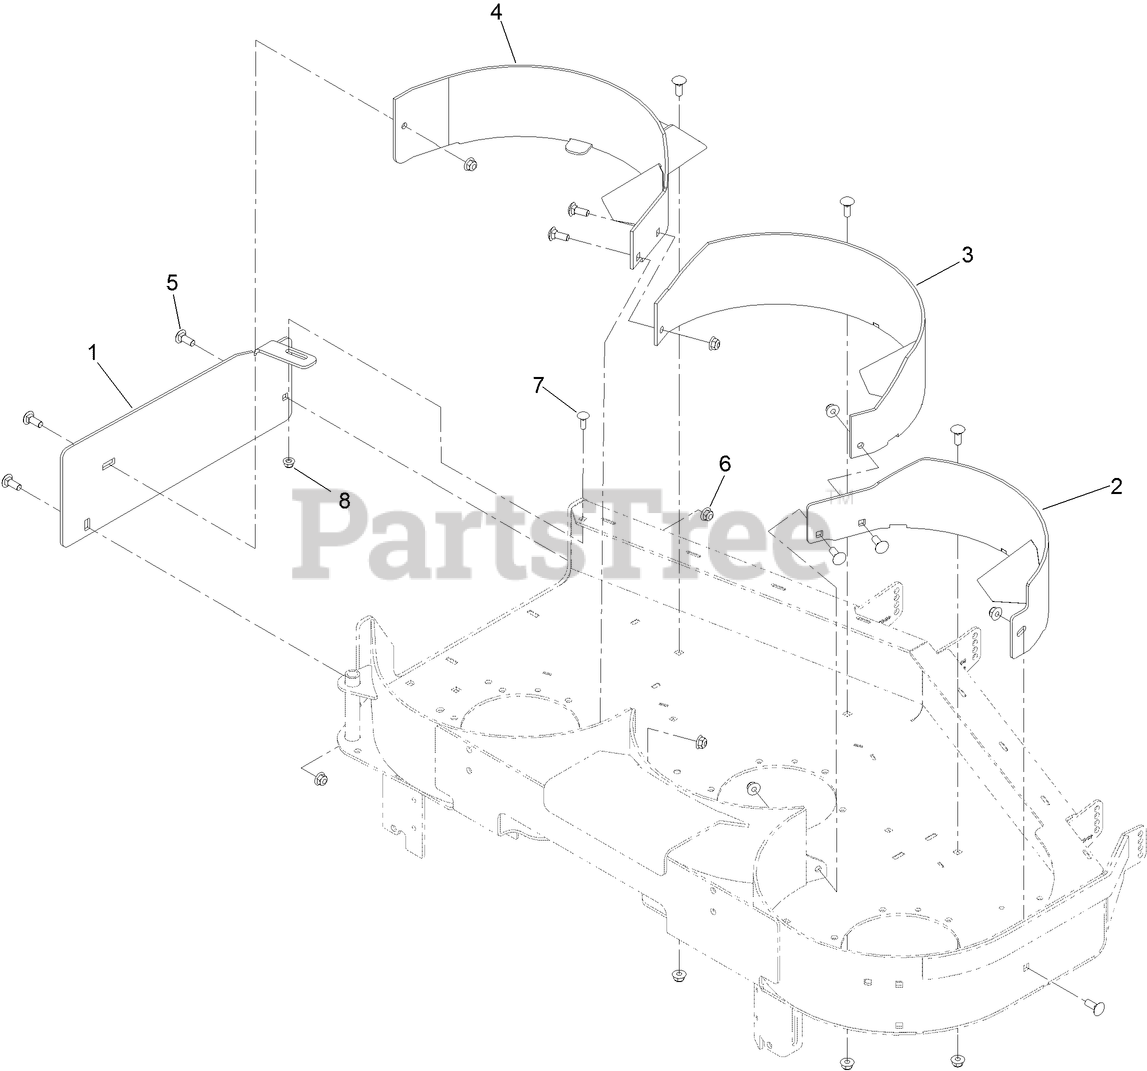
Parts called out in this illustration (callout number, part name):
1	PLATE-COVER, DISCHARGE
2	BAFFLE-LH
3	BAFFLE-CENTER
4	RH BAFFLE ASM
5	BOLT-CARR
6	NUT-HF, NI
7	SCREW-CARR
8	NUT-HF, NI
